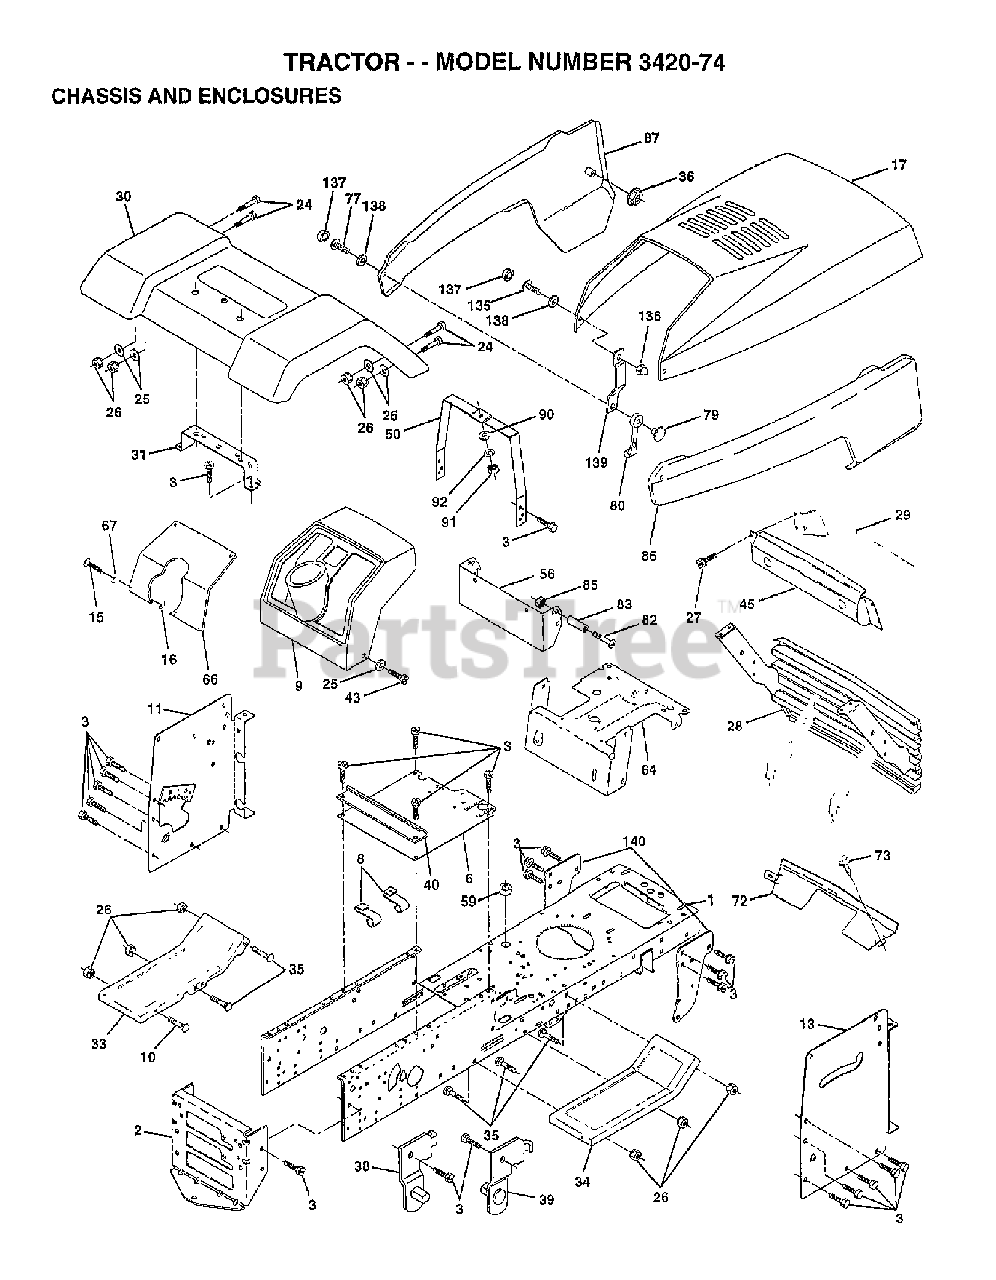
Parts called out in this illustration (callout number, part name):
6	SADDLE FLAT
8	CLIP,INSULATOR
17	Poulan TBD
25	WASHER
26	NUT
30	Poulan TBD
31	BRACKET.SUPPORT.FENDER
33	Poulan TBD
34	Poulan TBD
36	PAL NUT LT
38	BRACKET LH PIVOT
39	BRACKET RH PIVOT
43	SCREW GTV
50	DASH SUPT YP
64	DASH LOWER LT
66	Poulan TBD
67	WASHER
72	Poulan TBD
73	SCREW CRT
79	NUT.WELD
80	LATCH.HOOD.
82	SCREW
83	SPACER LT
85	NUT **
86	Poulan TBD
87	Poulan TBD
90	WASHER PM
91	NUT
92	LOCKWASHER
135	SCREW 10-24X3/8
136	NUT
137	SNAP CAP LT
138	WASHER LT
139	BRACKET.SUPPORT.HOOD/PANEL.NLA
140	BRACKET SUSPENSION FRONT
